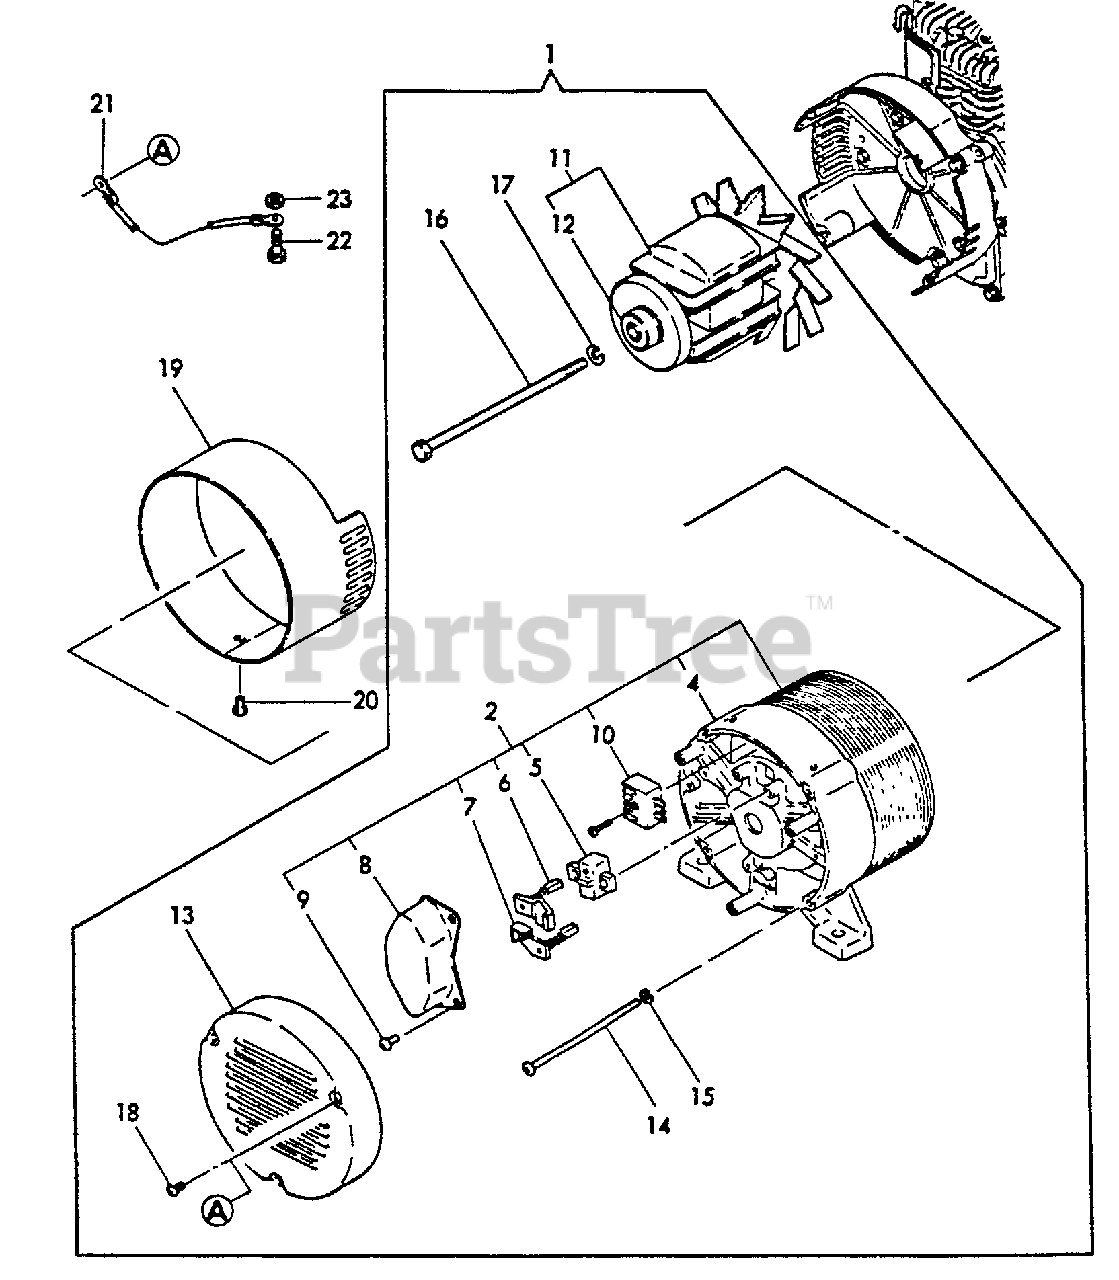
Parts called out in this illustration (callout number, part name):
1	GENERATOR 1.3 KVA
2	STATOR ASSY
4	COVER - REAR
5	HOLDER, BRUSH
6	BRUSH - ( + )
7	BRUSH - ( - )
8	A.V.R.
9	SCREW - 5×14
10	RECTIFIER
11	BEARING, BALL
12	BEARING, BALL
13	COVER
14	BOLT
15	LOCKWASHER - 6
16	BOLT
17	LOCKWASHER - 8
18	SCREW - 4×8
19	BAND
20	BOLT - 6×8 -- PLATED
21	WIRE, EARTH
22	BOLT - 6×16 -- PLATED
23	LOCKNUT - 6 -- PLATED
